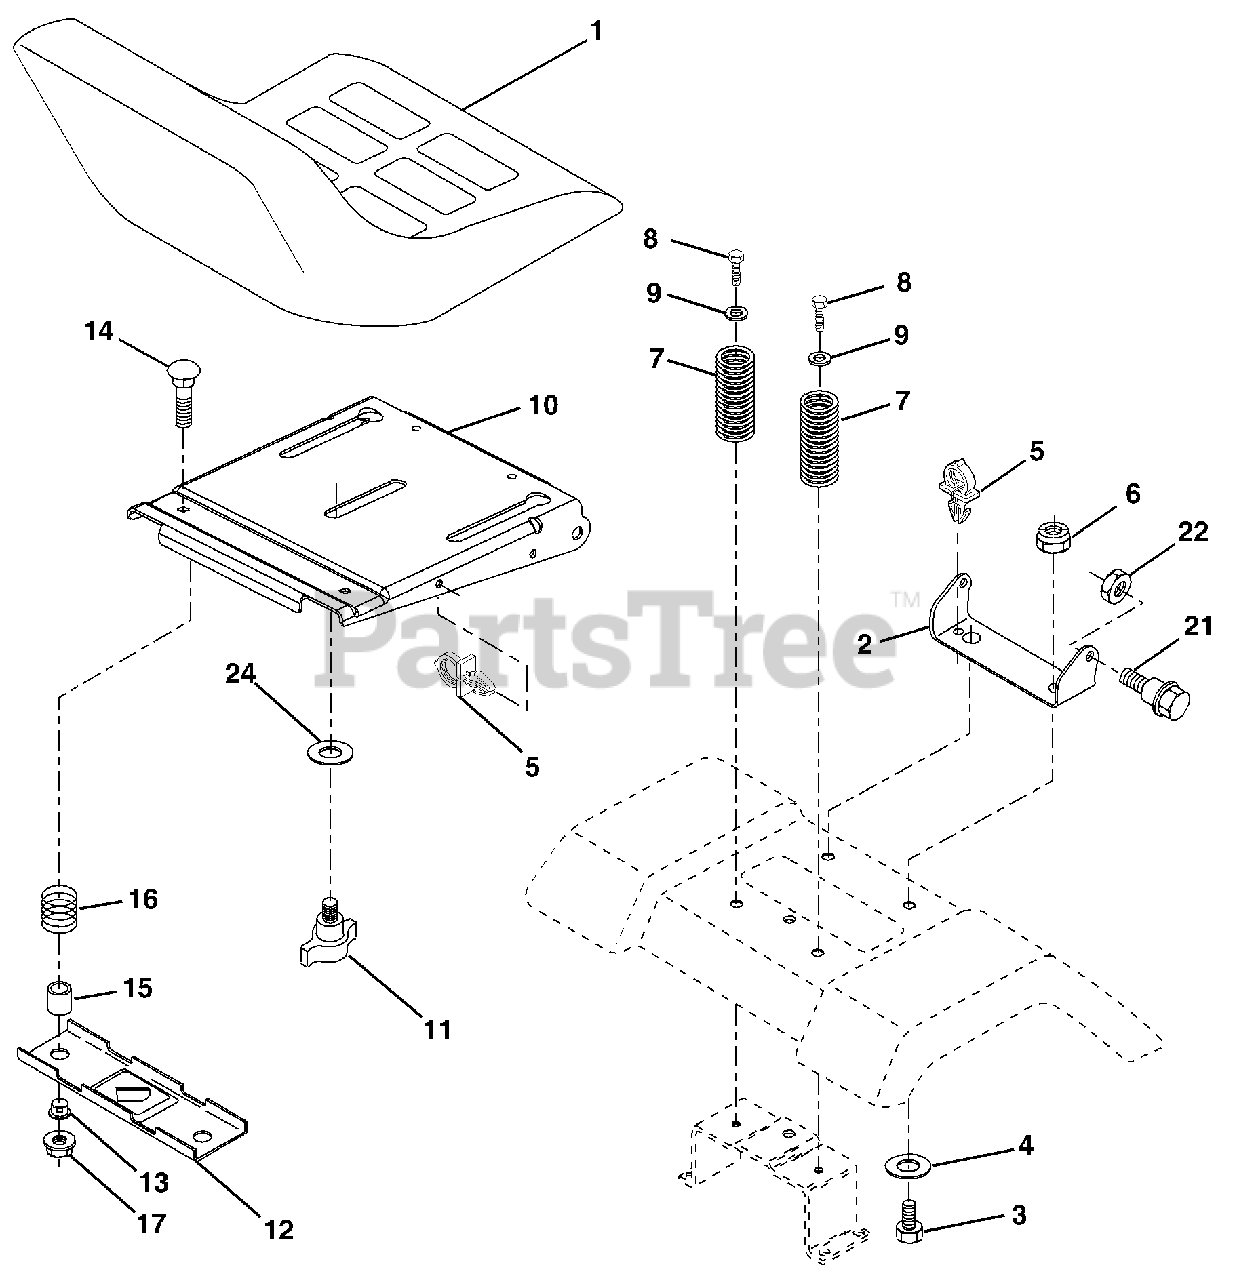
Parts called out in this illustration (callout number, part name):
1	Seat
2	Bracket Pivot
3	Bolt Hex 3/8-16unc x 1
4	Washer 13/32 x 1 x 10 Ga
5	Clip Push-In Hinged
6	Nut Lock Hex w/Ins. 3/8-16 Unc
7	Spring Seat Cprsn 2 250 Blk Zi
8	Screw 3/8-16 x 1.5 SMGML
9	Washer 13/32 x 1 x 14 Ga
11	Knob Seat Adj Wingnut
12	Bracket Mounting Switch
13	Bushing Snap Blk Nyl 50 Id
14	Bolt Rdhd Sht Nk 1/4-20 x 1-1/2
15	Spacer Split 28x 88 Zinc
16	Spring Cprsn 1 310 Blk Pnt
17	Nut Lock 1/4 Lge Flg Gr 5 Zinc
21	Bolt Shoulder 5/16-18 Unc-2A
22	Nut Lock 5/16-18
24	Washer 17/32 x 1-3/16 x 12 Ga
